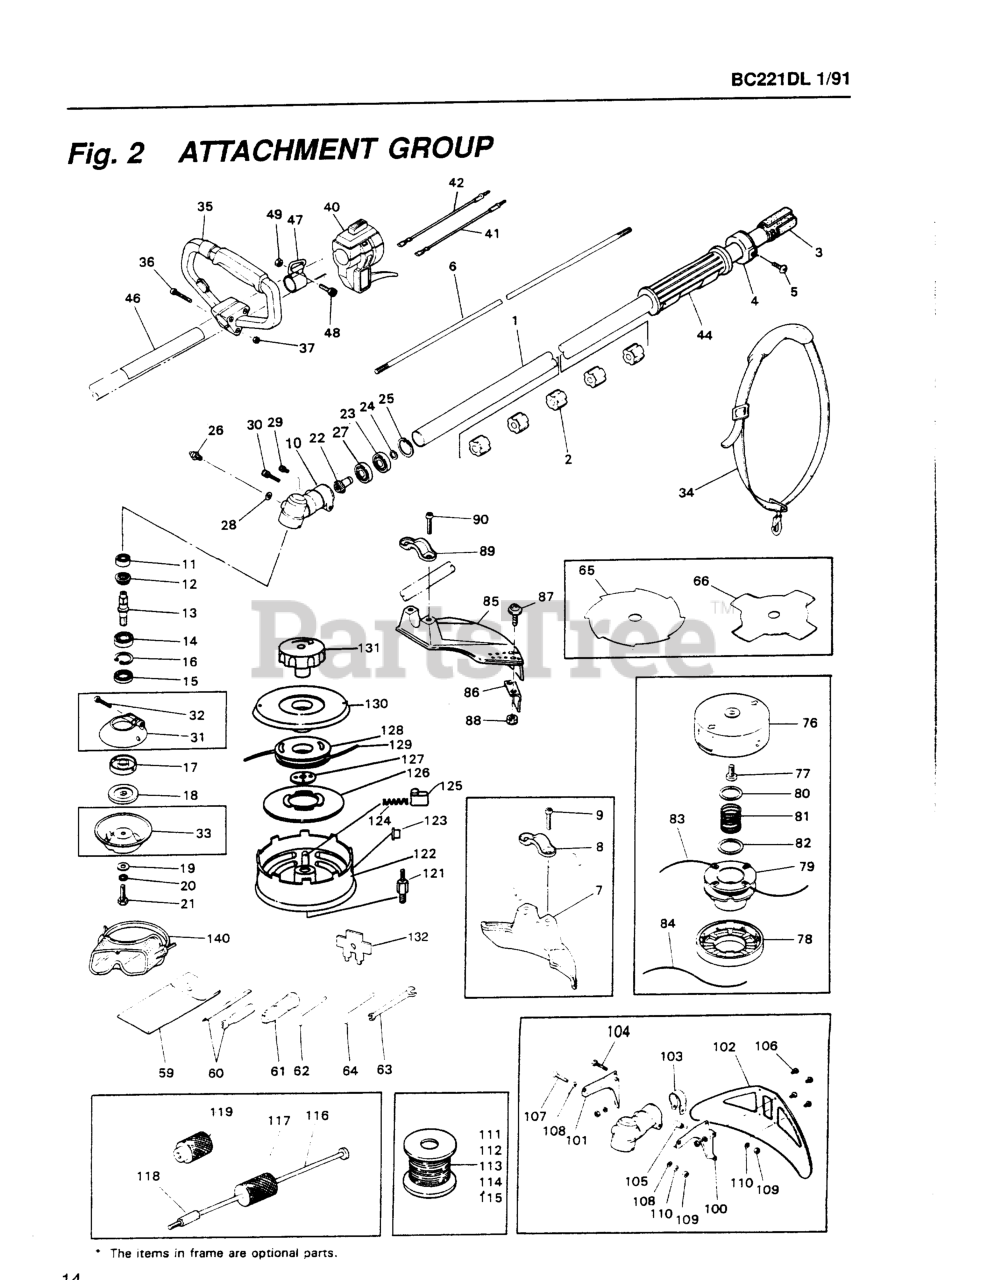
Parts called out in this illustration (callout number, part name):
4	CAP
5	SCREW, M5 X 10
8	CLAMP (REPLACES 5807-24120)
9	BOLT, M6 x 1.30
12	GEAR
14	BEARING (RPLS T3403-13510)
15	SEAL, OIL
16	RING, SNAP, M26 X 1.2
17	HOLDER (A) (NLA)
18	HOLDER (B)
19	WASHER
20	WASHER
21	BOLT
23	BEARING (RPLS T3300-13531)
24	RING, SNAP (RPLS T3300-13330)
25	RING, SNAP, M24 x 1.2
26	FITTING, GREASE
27	BEARING (RPLS T3403-13530)
28	WASHER, M6 X .8
29	BOLT, M5 X 10
30	BOLT
31	COVER (USE -13402)
32	SCREW, M4x25 (RPLS.0260-30425)
35	HANDLE ASSEMBLY (NLA)
36	SCREW, M5 x 30(RPLS 0263-00530
37	NUT, M5 X 4
41	CORD-A, BLACK
42	CORD-B, RED
46	PLATE, NAME (BC221DL)
47	HANGER COMP
48	BOLT, M5 X 10
49	NUT, M5 X 4
60	SCREWDRIVER
62	WRENCH (TOOL)
63	SPANNER, 8 X 10 (RPLS 2540- )
64	BAR
77	SHAFT (D)
80	PLATE, LARGE
82	PLATE, SMALL
86	BLADE
87	SCREW, M5 x 12
88	NUT
89	CLAMP (REPLACES 5807-24120)
90	BOLT, M6 x 1.30
100	BRACKET (A)
102	GUARD (NLA)
103	CLAMP (NO LONGER AVAILABLE)
104	BOLT, M5 X 30
108	WASHER, M5x.8(RPLS 01624-20508
109	NUT, M5 X 4
110	WASHER, SPRING M4 x 1.3
116	SHAFT (TOOL)
119	BLOCK (TOOL)
121	ADAPTER-MALE
122	HOUSING, SPOOL
123	EYELET (RPLS -15220)
124	SPRING, RED
125	SLIDE CAM (1 PC)
126	CAM DISK
127	NUT, FLAT
132	FASTENING TOOL
